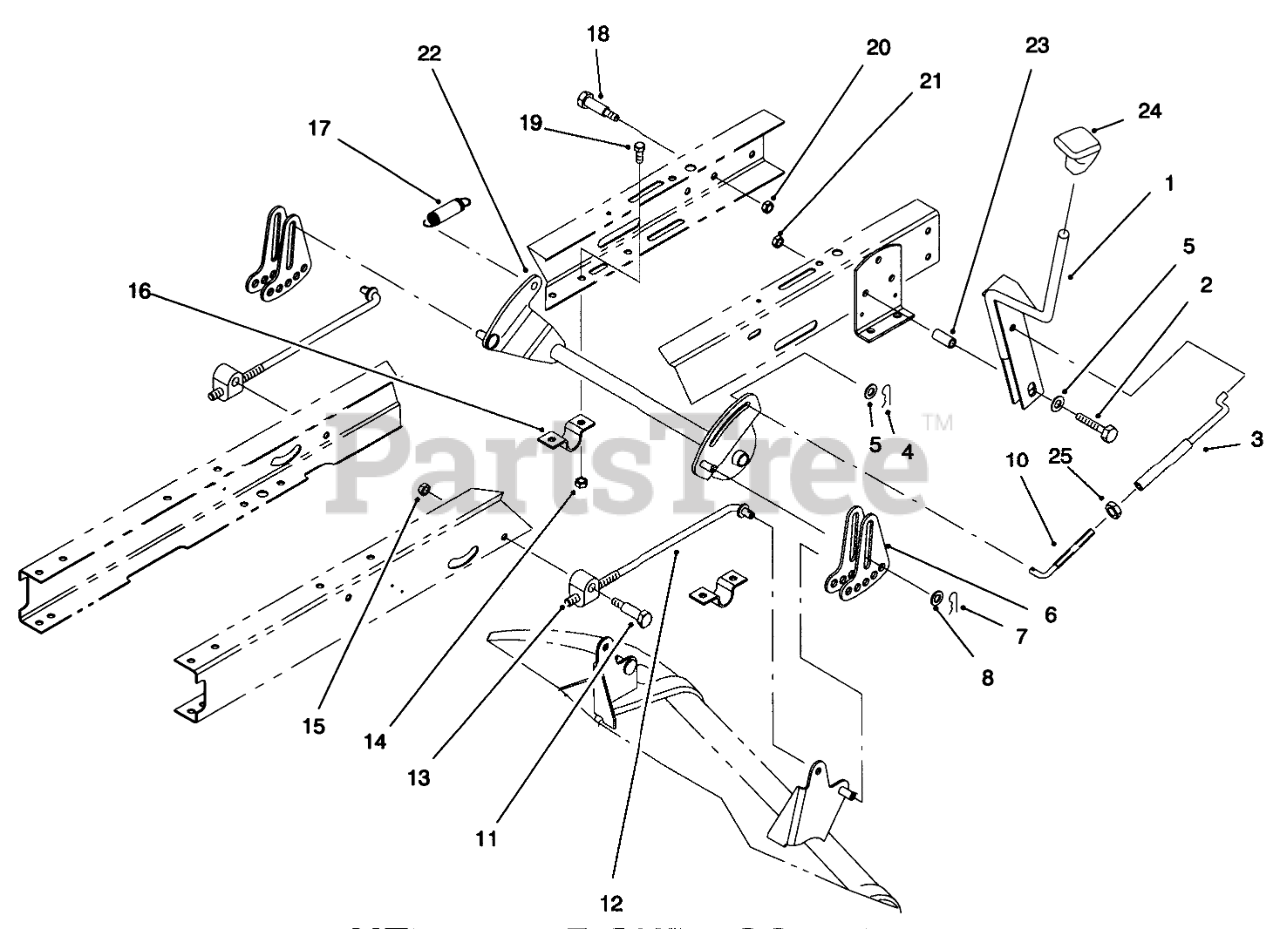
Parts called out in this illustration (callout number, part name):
1	Lever-H.O.C.
2	SCREW-HH
4	PIN-COTTER
5	Washer-Flat
6	Link-Adjusting H.O.C
7	PIN-COTTER
8	WASHER-HARDENED
10	LINK-HOC
11	SCREW-SHOULDER, HH
12	ROD-HANGER, REAR
13	TRUNNION-HOC
14	NUT-LOCK, NI
15	NUT-LOCK, NI
16	CLAMP-PIVOT, HOC
17	SPRING-EXTENSION
18	SCREW-SHOULDER, HH
19	SCREW-HH
20	NUT-LOCK, NI
21	NUT-LOCK, NI
22	Pivot-H.O.C.
23	SPACER
24	KNOB-SHIFT
25	NUT-JAM
